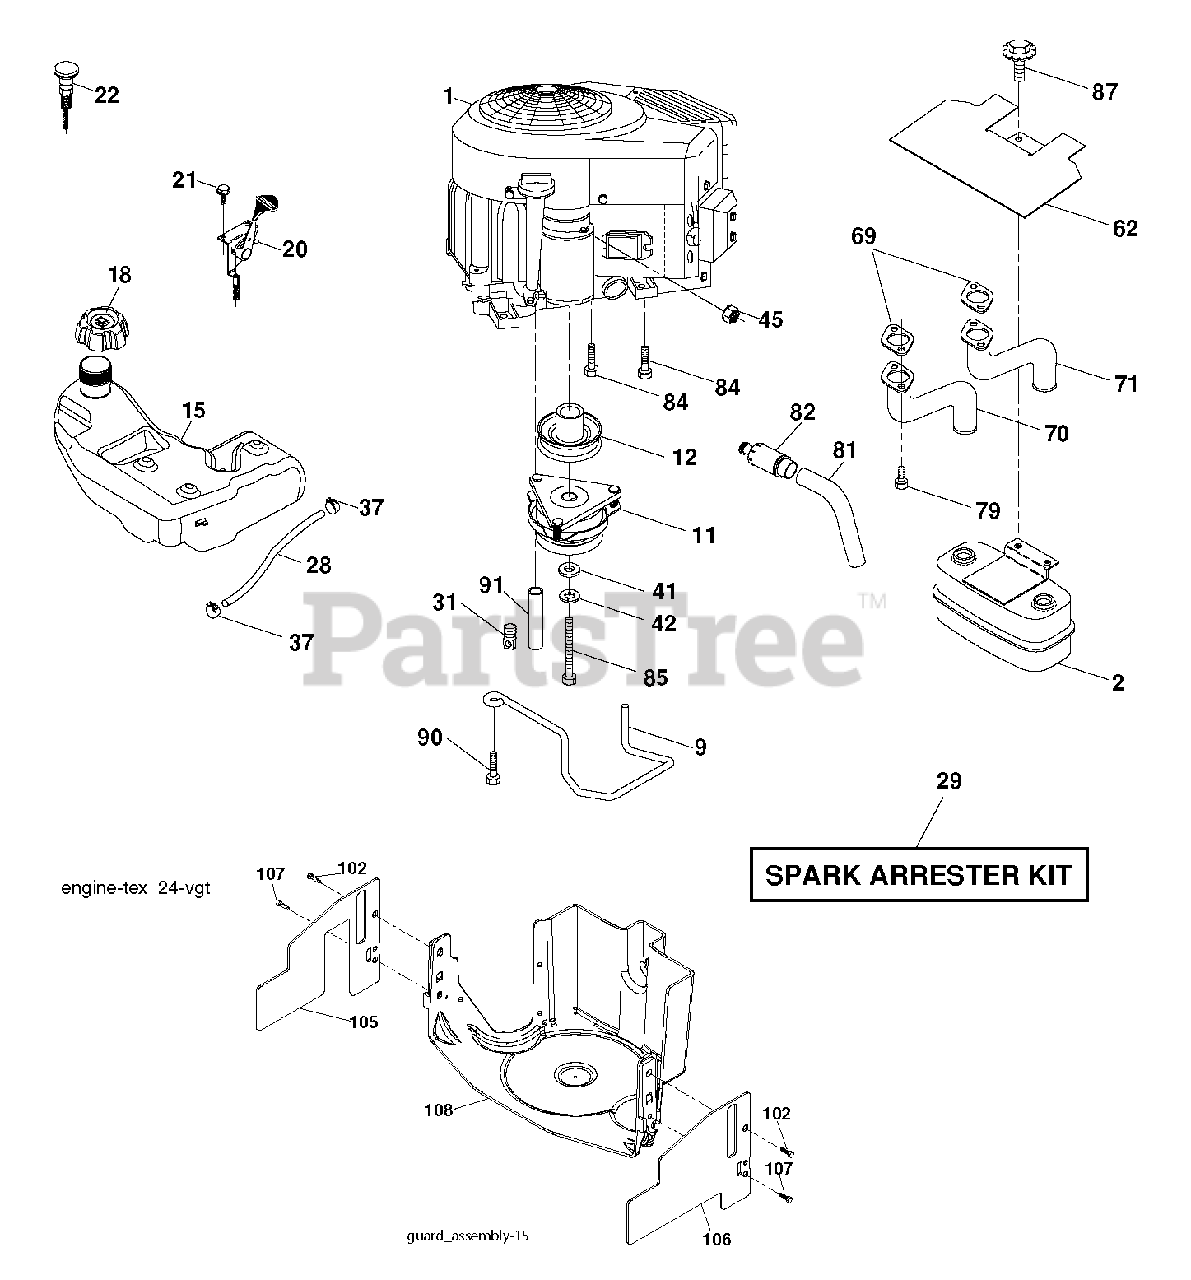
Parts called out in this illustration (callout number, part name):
2	MUFFLER.TWIN.CYL.LOW.TONE
9	KEEPER.BELT.ENGINE.3.25
11	CLUTCH
12	PULLEY.ASM.ENG.OGURA.3
15	TANK.FUEL.4GAL
18	CAP.ASM.FUEL.TANK.3"BL
20	THROTTLE CABLE
21	SCREW
22	CONTROL CHOKE
29	ARRESTER SPARK (OPTIONAL)
31	PUSH CLIP
37	HOSE CLAMP
42	LOCKWASHER
45	NUT
62	RP SHIELD HEAT MUFFLER
69	GASKET.MUFFLER
70	TUBE MANIFOLD LH
71	EXHAUST TUBE RH
79	SCREW.SOCKET.HEAD.5/16-18
81	TUBE, DRAIN OIL ASM.
82	PLUG DRAIN OIL EASY
84	SCREW.3/8-16
85	BOLT HEX 7/16-20X4-1/4"
87	BOLT.5/16-18UNCX1.W/SEMS.BLK
90	SCREW 3/8-16X1
91	BUSHING.1.375OD
102	SCREW
107	SCREW.1/4-20X5/8
